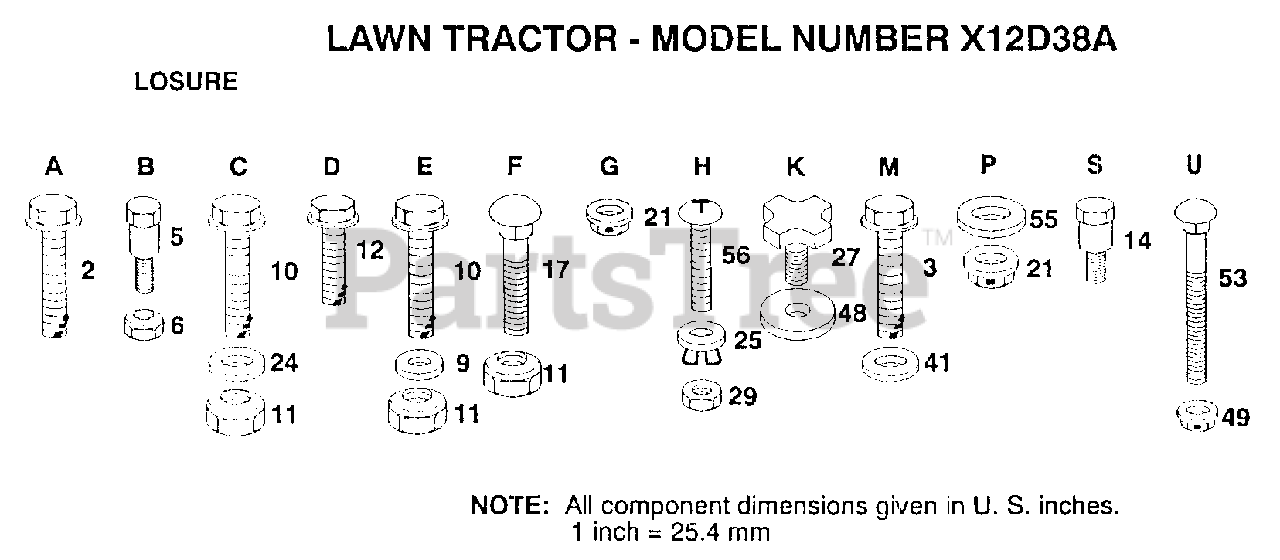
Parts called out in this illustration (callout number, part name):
2	SCREW
3	SCREW GTV
9	WASHER
12	SCREW LT
17	BOLT
21	PAL NUT LT
24	WASHER
25	RETAINER
27	"KNOB 1/2"" YT"
29	"GROMMET,PLASTIC"
41	WASHER
49	WASHER
53	BOLT
56	"SCREW,SPECIAL"
